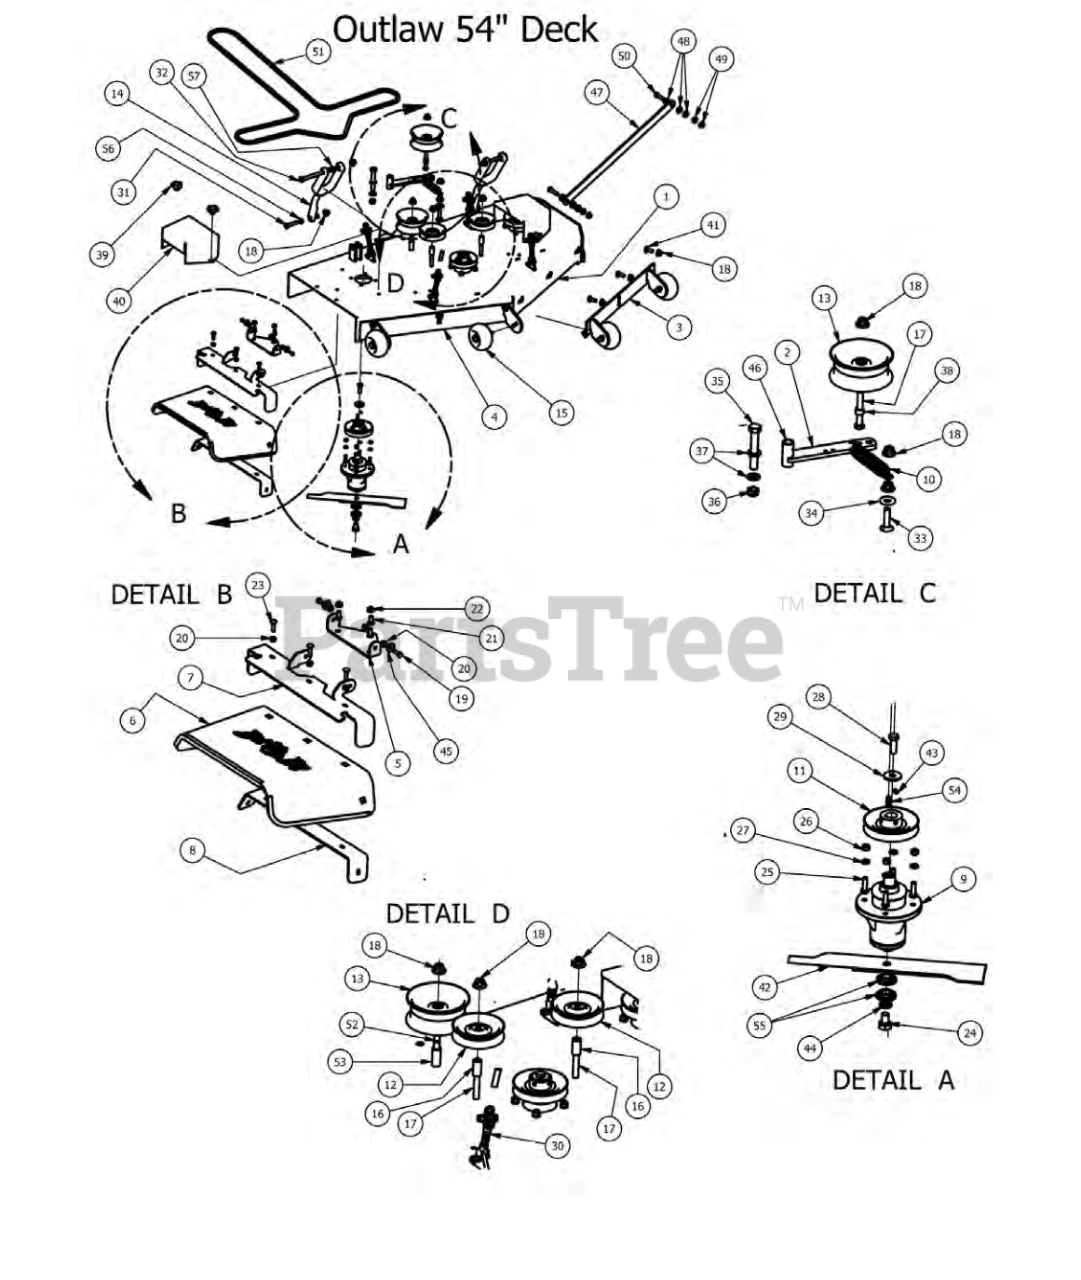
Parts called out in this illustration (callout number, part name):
1	54" Outlaw Deck
2	Deck Idler Bracket
3	54 Outlaw Adjustable Deck Front (Right)
4	54 Outlaw Adjustable Deck Front (left)
5	Discharge Chute Hanger (deck mounted)
6	Rubber Discharge Chute
7	Dischurge Chute Upper Hanger
8	Lower Hanger
9	Double Bearing Spindle
10	2009 Deck/Pump Idler Spring
11	5" Deck Pulley
12	4 3/4" Idler Pulley
14	Deck Hanger
15	Deck Wheel
16	Pulley Spacer
17	1/2 x 3 1/2 Flange Bolt Grade 8
18	1/2-13 Nylon Flange Nut-Orange
19	5/16" x 1" Bolt
20	5/16" Flange Nut
21	3/8" x 3/4" Hex Bolt
22	3/8" Flange Nut
23	5/16" x 1 1/4" Carriage Bolt
24	5/8" x 1 1/2" Grade 8 Bolt
25	3/8" x 1 1/4" Hex Bolt
26	3/8-16 Hex Nuts Zinc
27	3/8" Lock Washer
28	1/2"-20 x 1 1/2 - Grade 5 Fine Thread Bolt
29	1/2 Belleville Washer
30	2-Link Adjustable Deck Hange
31	1/2-13X 2-1/4 GR Hex Bolts
32	1/2" x 5 1/2" Bolt
33	1/2 x 2" Carriage Bolt
34	1/2" Flat Washer
35	5/8" x 4" Hex Bolt
36	5/8" Nylock (1/2 Jam)
37	.635 ID Plastic Washer
38	Spacer 3/4 OD x 1/2 ID x .75
39	5/16" Knob
40	Pulley Cover
41	1/2" x 1 1/4 Carriage Bolt
42	54" Deck Fusion Blade For Outlaw
43	3/8" Set Screw
44	5/8" Lock Washer
45	360 ID Plastic Washer
46	Deck Idler Assembly Componets13,18,17,38,2
47	Outlaw Panhard Link
48	.505 Nylon Spacer
49	1/2" Flange Nut
50	1/2-13x2 GR 5 Hex Bolt
51	B165 Belt-60 54" deck Outlaw
52	1/2" x 4" Bolt (Grade 8)
53	1 3/4" Pulley Spacer
54	1/4" x 1" Key
55	Double Bearing For Spindle
56	Flange for Lower Deck Arm
57	Flange Bushing for Deck Arm Upper
